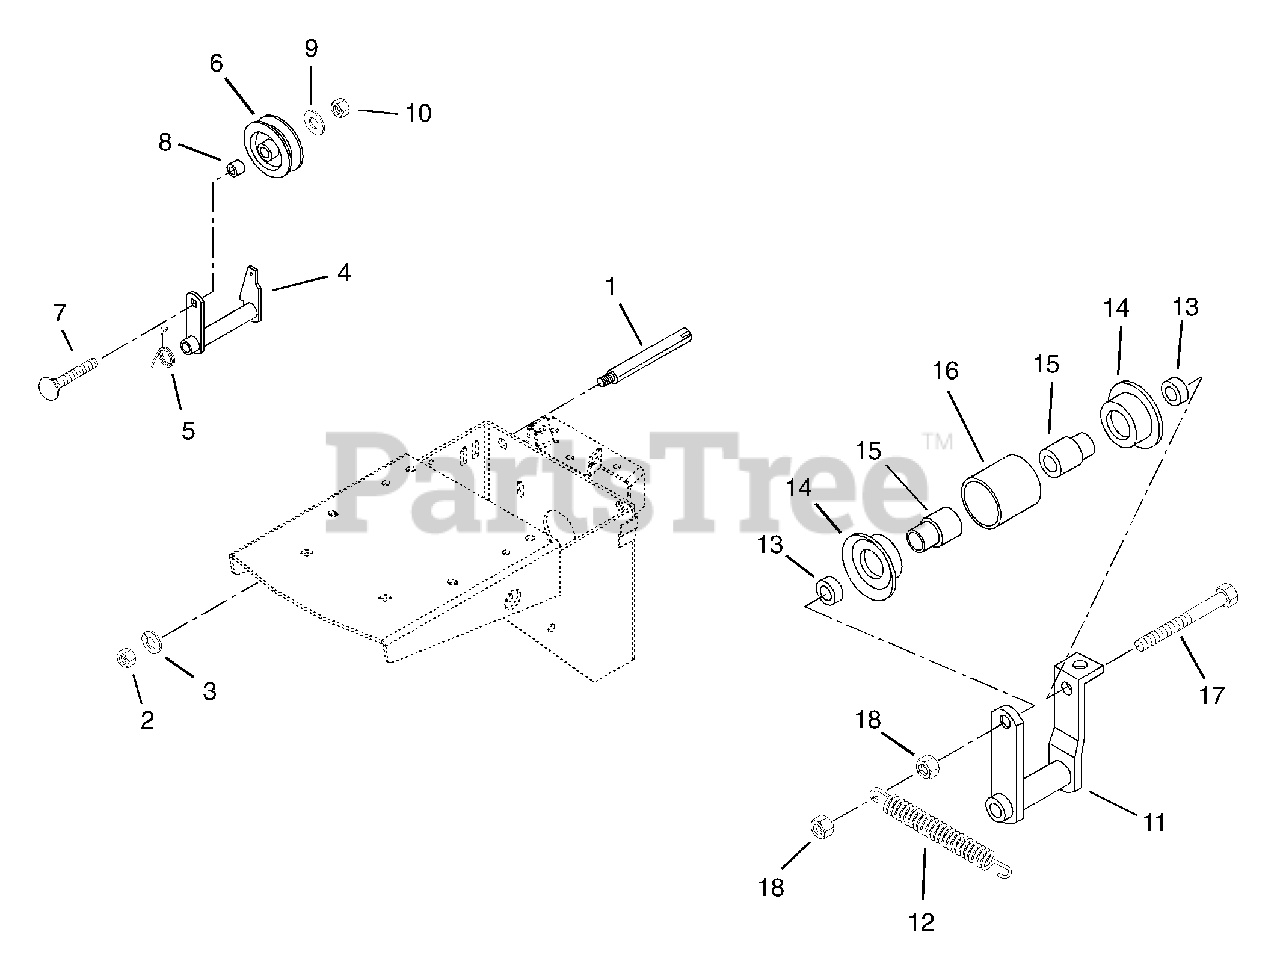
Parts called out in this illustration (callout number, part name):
1	IDLER PIN
2	@NUT-HEX .38-16 YWZC
3	@WSHR-LK .38X.094 REG YWZC
4	ARM, REVERSE IDLER
5	SG-TORS
6	IDLER
7	@BLT-RDHDSQNK .31-18X1.50 G5YZ
8	SPCR, BRG .315X.50X.688X.281
9	@WSHR-FL-STL.38X.875X.083 YWZC
10	@NUT-HEX .31-18 YWZC
11	IDLER ARM
12	SG-TENS .063X.44X2.81 WLD 18
13	BSHG, SPCR.500X.750X.321 PM
15	BEARING SPACER
17	@BLT-HEX .31-18X4.00 GR5 YWZC
18	@NUT-LK-CTR .31-18 YWZC
